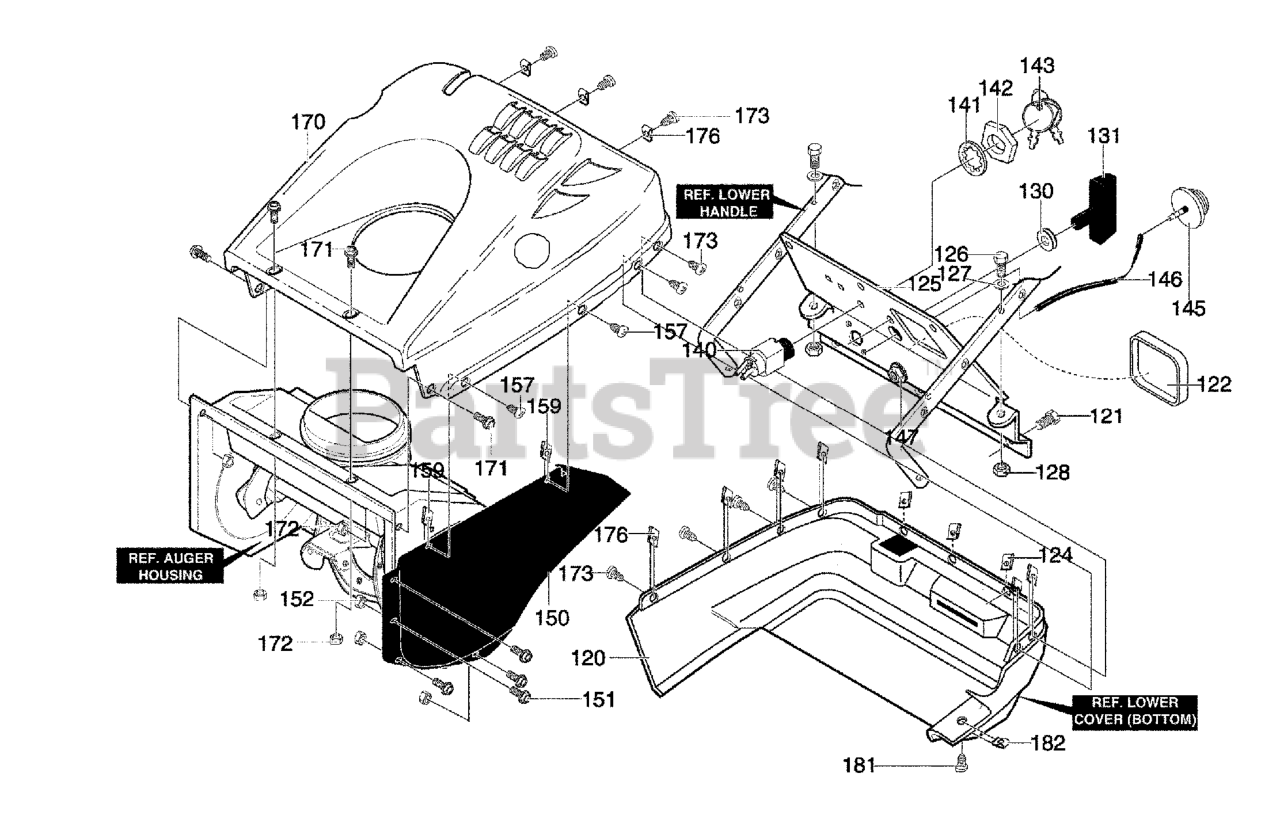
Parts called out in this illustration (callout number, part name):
120	COVER, BOTTOM
121	SCREW, 1/4-14X.75
122	PANEL, SPARK ACCESS
124	NUT, 1/4-10 SPEED J TYPE
125	CONTROL PANEL
126	SCREW, 1/4-20X1.25
127	FLATWASHER
128	NUT, 1/4-20
130	GOMMET & WASHER
131	KNOB T
140	SWITCH, IGNIT.
141	WASHER
142	NUT. 5/8-32
143	KEYS & RING
145	PRIMERBULB
146	HOSE PRIM 5.75LG
147	NUT, 1/4-20
150	COVER, BELT
151	SCREW, 10-24X.50
152	NUT, #10-24
157	SCREW, 1/4-14X.75
159	NUT, 1/4-10 SPEED J TYPE
170	COVER, TOP
171	SCREW,#10-24X.50
172	NUT #10-24
173	SCREW, 1/4-14X.75
176	NUT, 1/4-10 SPEED J TYPE
181	SCREW, 1/4-14X.75
182	NUT 1/4-10 SPEED J TYPE
